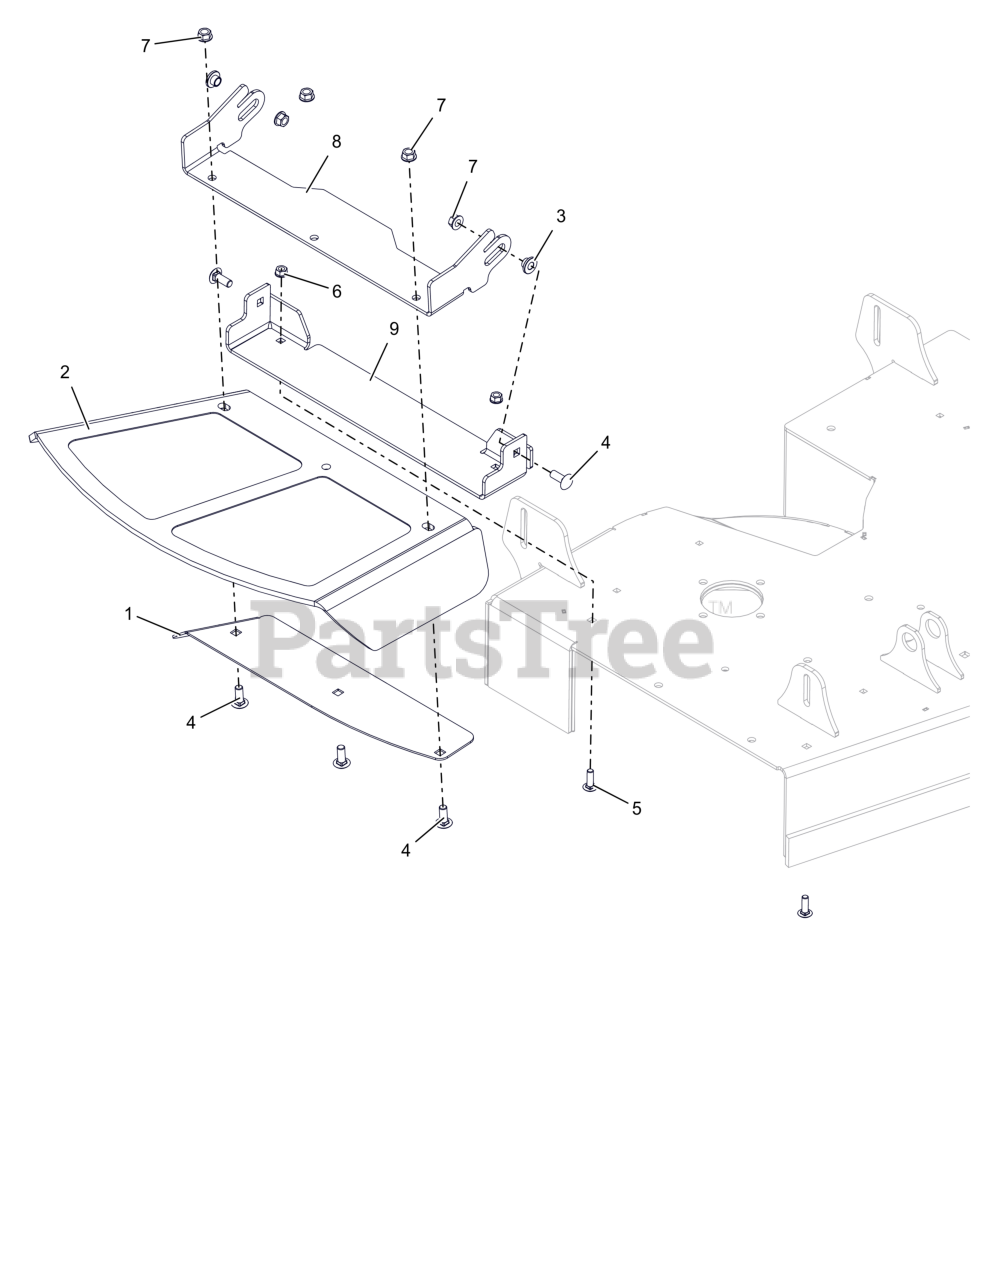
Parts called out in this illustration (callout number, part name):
1	48-60 DISCH CHUTE CLMP PLT-BLK
2	CHUTE,48-60" FRMD RUBBER DISCH
3	BSHG-FLG .385X.500X.875X.406
4	BLT,RHSSN .38-16X1.00 G5 ZCC
5	BLT,RHSSN .31-18X1.00 G5 ZCC
6	NUT,LK-CTR-FLG .31-18 GF ZCC
7	NUT-LK-CTR-FLG .375-16 GF ZCC
8	BRKT- 32" CHUTE MTG (RED)
9	32" DISCH CHUTE MTG W/SAFETY
